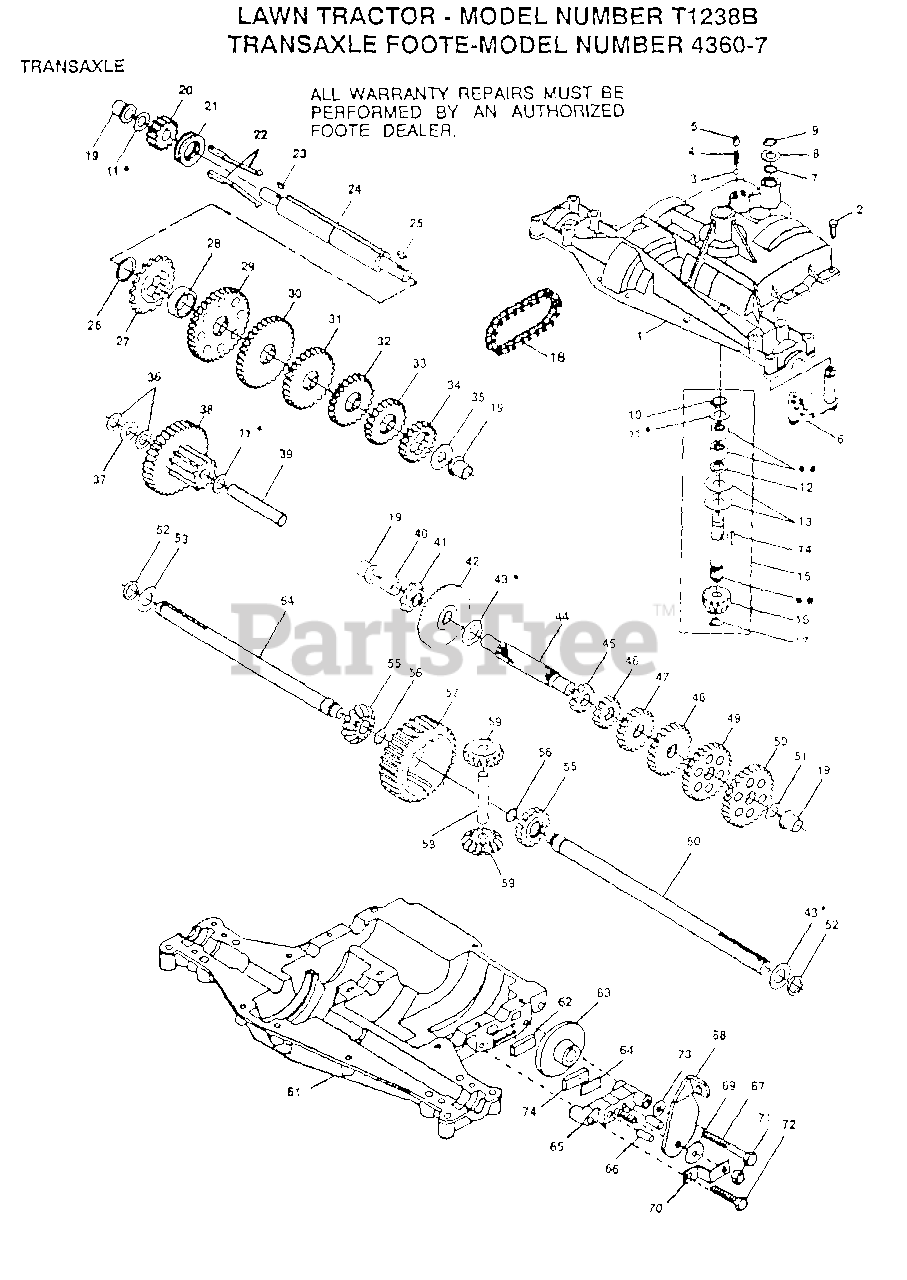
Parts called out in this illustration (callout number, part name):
1	HOUSING UPPER
3	BALL DETENT
4	SPRING, DETENT
5	SCREW, SET
6	ASSY SHIFTER
8	WASHER PLAIN
8A	WASHER PLAIN
8B	WASHER PLAIN
8C	WASHER PLAIN
8D	WASHER PLAIN
8E	WASHER PLAIN
8F	WASHER PLAIN
9	RING RETAINING
10	RING RETAINING
11	WASHER PLAIN
11A	WASHER PLAIN
11B	WASHER, PLAIN .632 X 1.00 X .026
11C	WASHER PLAIN
11D	WASHER PLAIN
11E	WASHER PLAIN
11F	WASHER PLAIN
11G	WASHER PLAIN
11H	WASHER, PLAIN .632 X 1.00 X .060
11I	WASHER PLAIN
13	WASHER, PLAIN .632 X 1.38 X .046
14	KEY WOODRUFF #9
15	ASSY KIT INPUT SHAFT
16	PINION, BEVEL, 14 TEETH
17	RING, RETAINING
18	CHAIN, 24 PITCHES
19	BEARING, FLANGE
20	GEAR SPUR, 14 TEETH
21	COLLAR CLUTCH
22	KEY CLUTCH
23	KEY WOODRUFF #3
24	SHAFT INTERMEDIATE
25	KEY, WOODRUFF, #61
26	RING, RETAINING
27	SPROCKET, 18 TEETH
29	GEAR, SPUR, 37 TEETH
30	GEAR, SPUR, 35 TEETH
31	GEAR, SPUR, 30 TEETH
32	GEAR, SPUR, 25 TEETH
33	GEAR, SPUR, 22 TEETH
35	WASHER, PLAIN .640 X 1.37 X .061
36	WASHER, PLAIN .632 X 1.00 X .026
37	SPACER .630 X 1.00 X .169
38	ASSY GEAR COMB 12&35 TEETH
39	SHAFT IDLER
40	SPACER .635 X .875 X .755
41	SPROCKET, 9 TEETH
42	GEAR, BEVEL, 42 TEETH
43	WASHER PLAIN
43A	WASHER PLAIN
43B	WASHER PLAIN
43C	WASHER PLAIN
43D	WASHER PLAIN
43E	WASHER PLAIN
43F	WASHER, PLAIN .758 X 1.25 X .031
43G	WASHER PLAIN
43H	WASHER PLAIN
43I	WASHER PLAIN
43J	WASHER PLAIN
43K	WASHER PLAIN
43L	WASHER PLAIN
44	SHAFT, DRIVE
45	GEAR, SPUR, 12 TEETH
46	GEAR SPUR, 15 TEETH
47	GEAR, SPUR, 20 TEETH
48	GEAR, SPUR, 25 TEETH
49	GEAR, SPUR, 28 TEETH
50	GEAR, SPUR, 31 TEETH
51	WASHER, PLAIN .632 X 1.00 X .060
53	WASHER PLAIN
54	AXLE LEFT HAND
55	GEAR, MITER, 15 TEETH
56	RING, RETAINING
57	GEAR, SPUR, 32 TEETH
58	SHAFT, CROSS
59	GEAR, MITER, 15 TEETH
60	AXLE, R.H.
61	HOUSING LOWER
62	PUCK, FRICTION
63	DISC, BRAKE
65	JAW, BRAKE
66	PIN, DOWEL
67	SCREW TAPPING
68	LEVER, ACTUATING
69	WASHER, PLAIN .321 X 1.00 X .055
70	BRACKET, ANTI-ROTATION
71	LOCKNUT 5/16-24
72	SCREW TAPPING
73	WASHER PLAIN
74	PUCK, FRICTION
